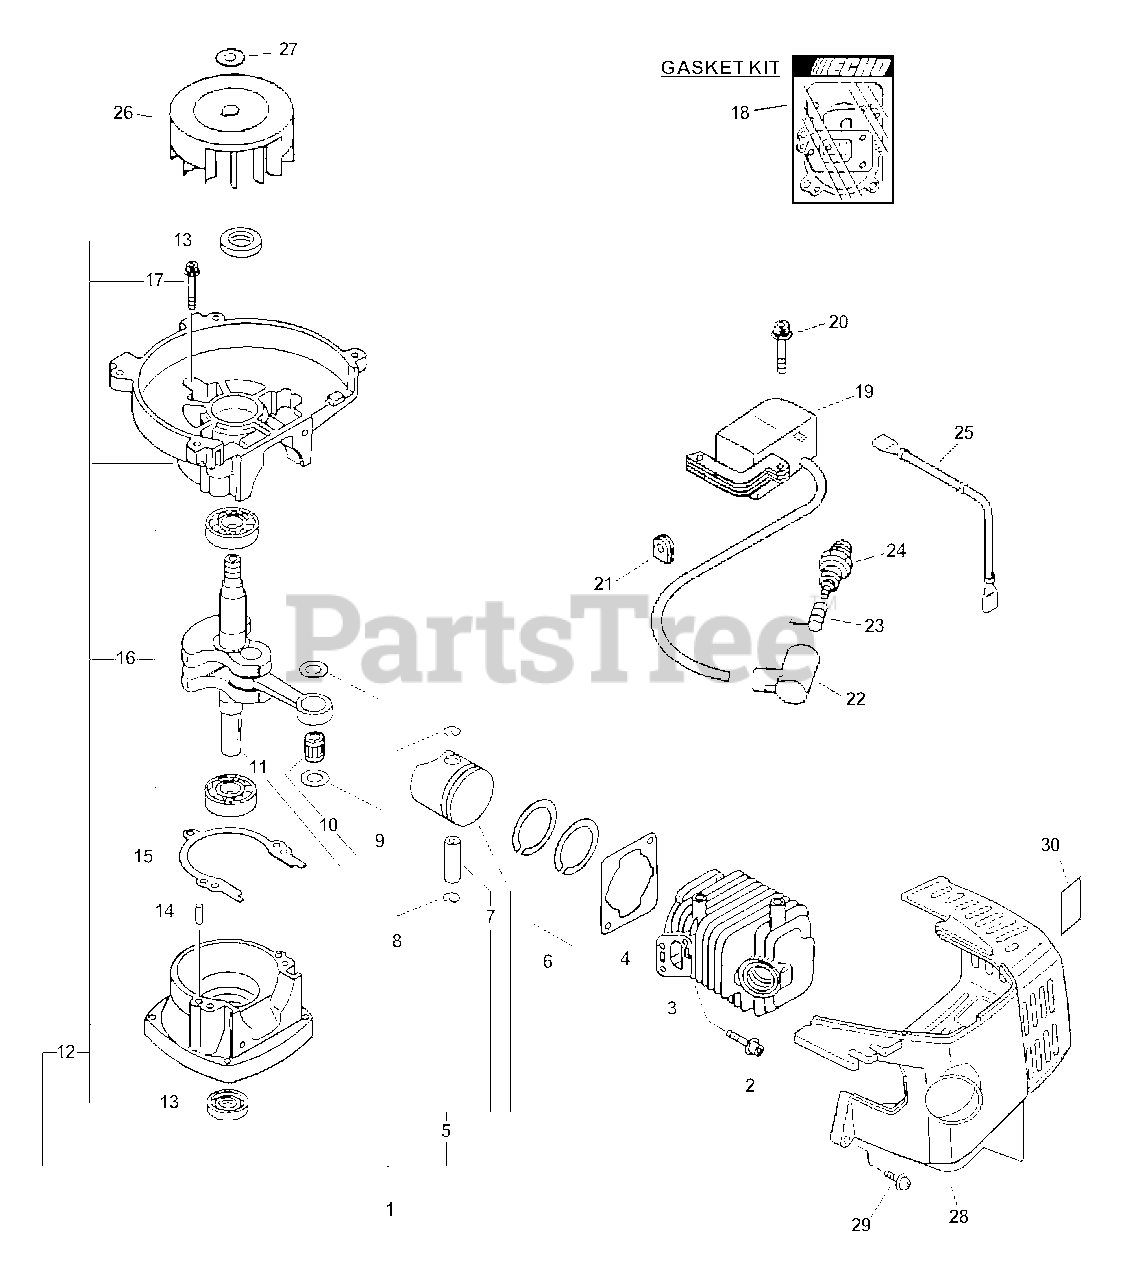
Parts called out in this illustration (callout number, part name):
1	SHORT BLOCK - SB1051
2	BOLT 5×22
3	CYLINDER
4	GASKET, CYLINDER
5	PISTON KIT
6	RING, PISTON
7	PIN, PISTON 8
8	RING, SNAP
9	WASHER, THRUST
10	BEARING, NEEDLE
11	CRANKSHAFT ASSY
12	CRANKCASE KIT
13	SEAL, OIL 12
14	PIN, LOCATING 4
15	GASKET, CRANKCASE
16	BEARING, BALL - 6201 C3
17	BOLT 5×28
18	GASKET KIT
19	COIL, IGNITION
20	SCREW 4×22
22	CAP, SPARK PLUG
23	TERMINAL, SPARK PLUG
24	SPARK PLUG - BPM-7Y
25	LEAD
26	FLYWHEEL
27	WASHER 8.5×16×1.2
28	COVER, ENGINE
29	SCREW 4×22
30	LABEL, CAUTION - HOT
